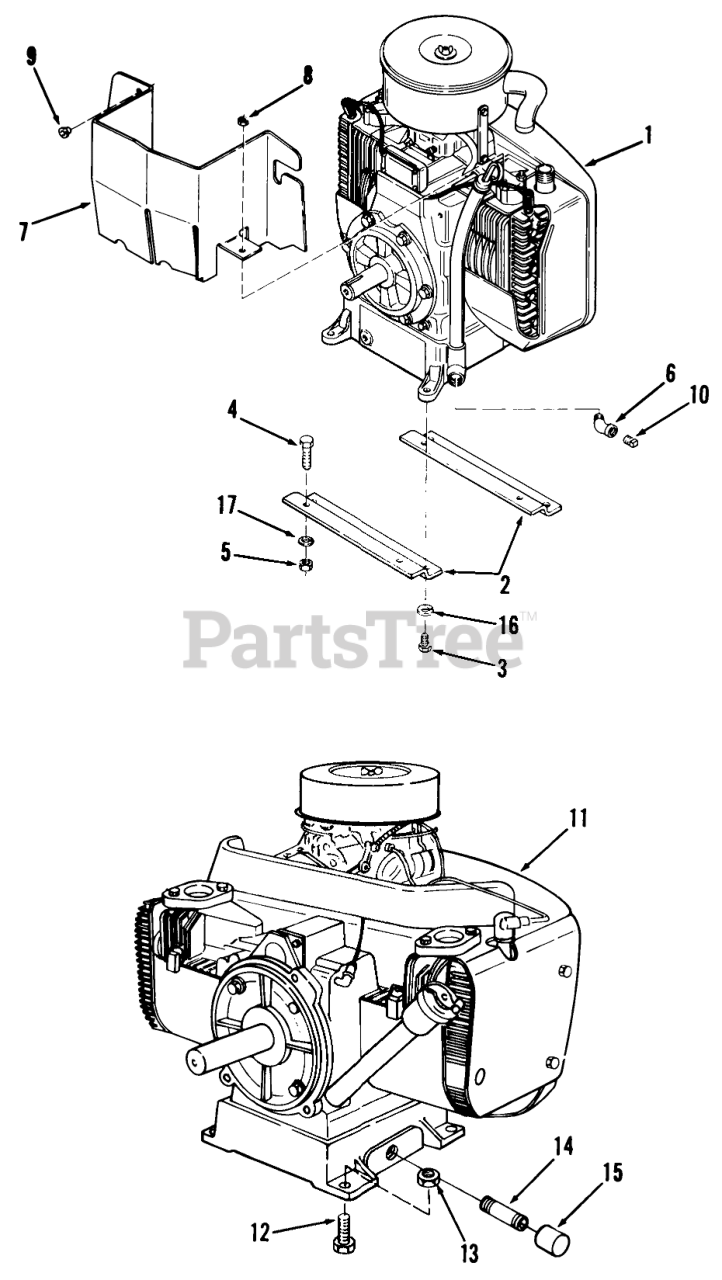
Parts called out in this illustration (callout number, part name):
1	Engine-16 HP Onan
2	Bracket-Engine
3	Bolt
4	Bolt
5	Eslok Nut
6	Street Elbow 1/2 X 45
7	Heat Shield
8	Nut
9	BUSHING-NYLON .75
10	ELBOW
12	Hhcs
13	Nut
14	Nipple 3/4 Pipe X2
15	Cap-3/4 Pipe
16	LOCKWASHER
17	Washer
